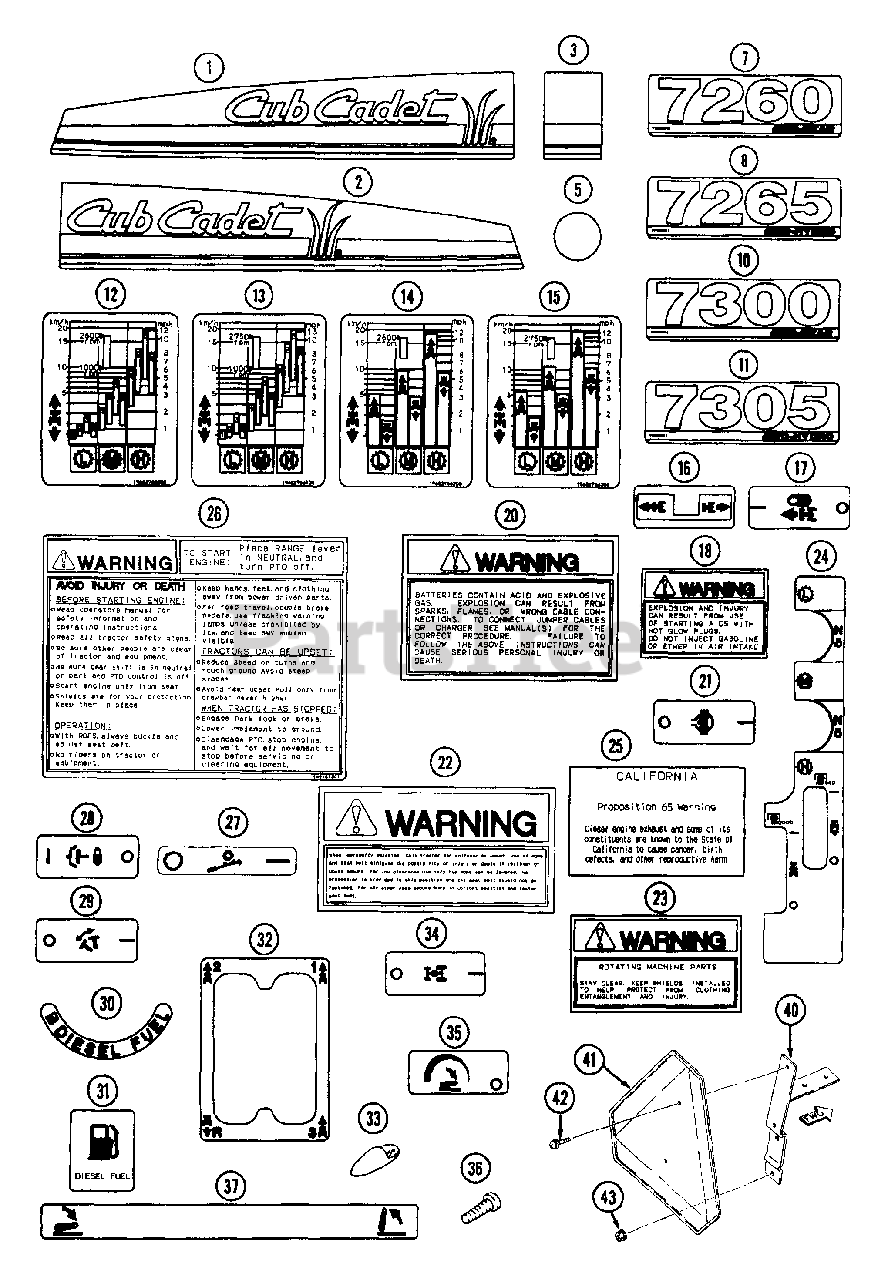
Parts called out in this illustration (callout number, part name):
1	Label, Side L.H.
2	Label, Side R.H.
10	Label, Model 7300
11	Label, Model 7305
12	Label, Speed G
13	Label, Speed G
14	Label, Speed H
15	Label, Speed H
16	Label, HST Control
17	Label, SP Control
18	Label, Warning
20	Label, Warning
21	Label, Diff. Lock
22	Label, Warning
23	Label, Warning
25	Label, Proposition 65
26	Label, Warning
28	Label, Declutch
37	Label, Position
41	Emblem, SMV
